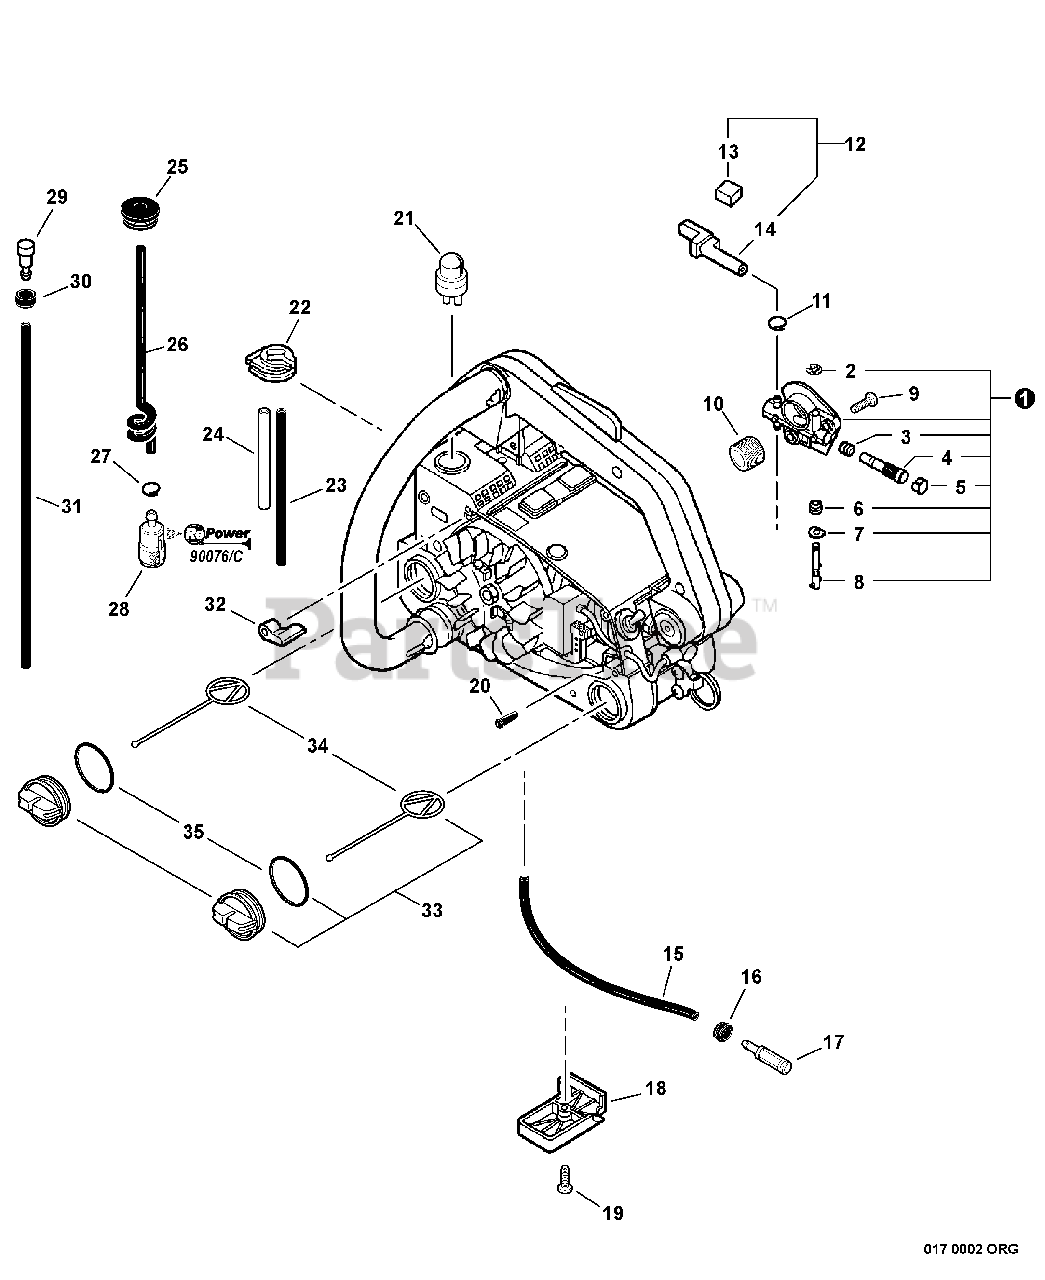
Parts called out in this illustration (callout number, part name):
1	AUTO-OILER ASSY
4	PLUNGER ASSY
5	CAP, OIL PUMP
8	ADJUSTER, OILER
9	SCREW 5×12
10	GEAR, WORM
11	CLIP Ø6.5 MM
12	PIPE KIT, OIL
13	PAD, FOAM
14	PIPE, OIL OUTLET
15	PIPE 3×6×115 BLACK
16	GROMMET
17	FILTER, OIL
18	COVER, BOTTOM
19	SCREW 4×16
20	VENT ASSY
21	BULB, PURGE
22	BRACKET, BULB
23	PIPE, FUEL 3x-5x-70 BLACK
24	PIPE, FUEL 2×4×42 CLEAR
25	GROMMET, FUEL
26	PIPE, FUEL 3×6×160
27	CLIP Ø6.5 MM
28	FILTER, FUEL
29	VENT ASSY
30	HOLDER, VENT
31	PIPE, FUEL 3×5×150 BLACK
33	CAP ASSY, OIL - BLACK
34	CONNECTOR, CAP L= 60 MM
35	O-RING 25
36	TUNE-UP KIT
